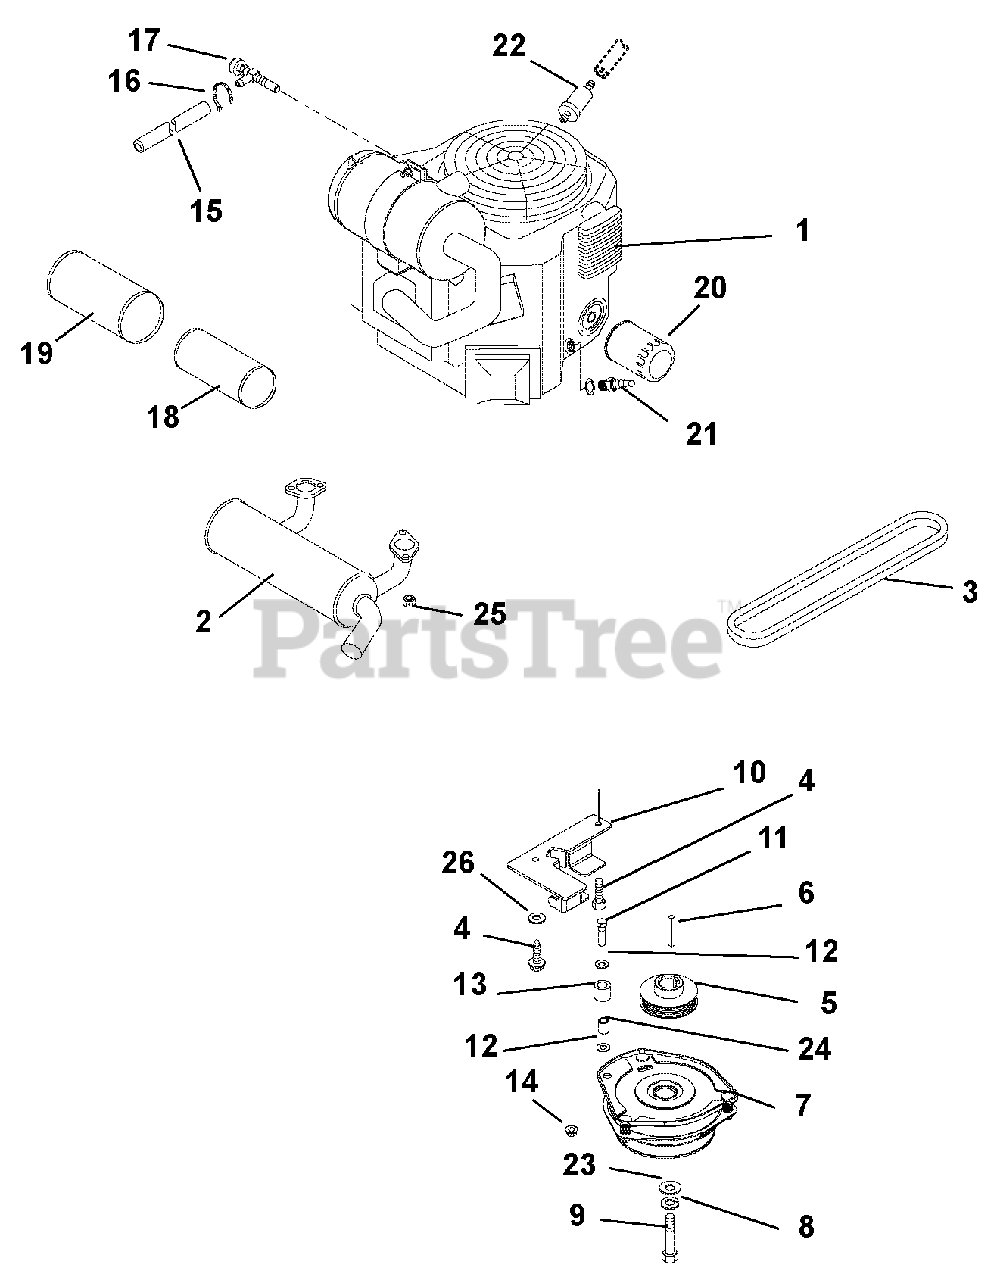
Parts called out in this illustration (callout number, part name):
1	Engine, Kawasaki (FX850V)
2	Muffler, Kawasaki Vertical
3	Belt, Poly-V
4	Bolt, Hex .38-16 x 1.25 G5 YZ NYTORQ
5	Sheave, Poly V 1.127 x 3.275
6	Key, Square .25 x 3.50 x .25 SA
7	Clutch, Electric
8	Washer, Locking .44 x .109
9	Bolt, Hex .44-20 x 1.50 Grade 5 YZ EP80
10	Anchor, Clutch
11	Bolt, Hex .38-16 x 1.50 Grade 5
12	Washer, Flat Steel .406 x .812 x .065
13	Bumper, Rubber .62 x 1.0 x .88 LG
14	Nut, Locking Top Flange .38-16
15	Gas Line, Bulk .25 I.D.
16	Cable Tie LG 5-1/2
17	Drain, 1/2" Drain
18	Element, Inner Safety
19	Element, Outer Primary
20	Oil Filter
21	Spark Plug
22	Fuel Filter
23	Washer, Flat Steel .469 x 2 x .25
24	Bushing, .407 x .625 x .813
25	Nut, Locking Top M8-1.25
26	Washer, 3/8" Spring Disc
